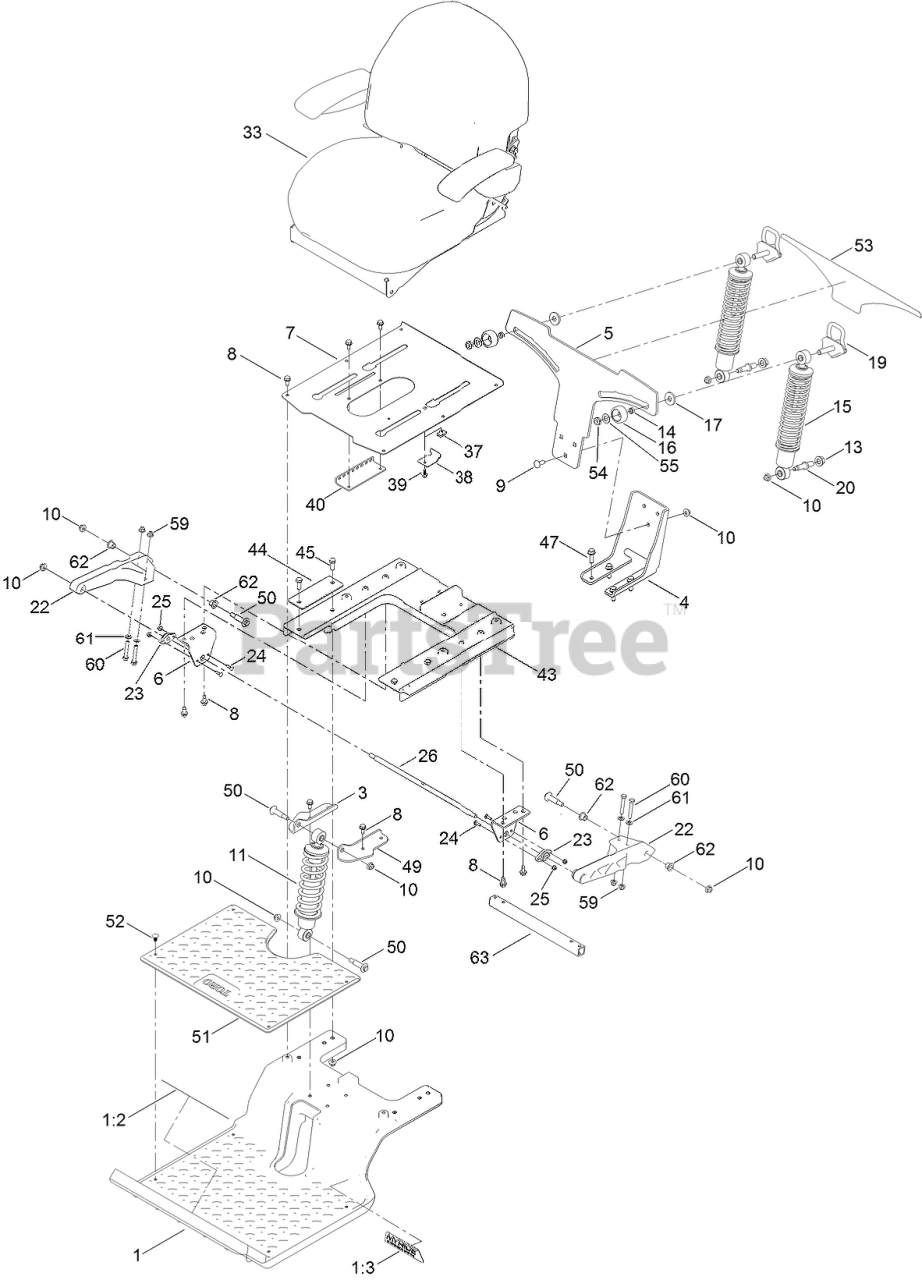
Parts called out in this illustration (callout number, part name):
1	SUBFRAME-FRONT
1:2	DECAL-DANGER
3	BRACKET-SHOCK MOUNT, UPPER (RH)
4	BRACKET-MOUNT, LOWER
5	BRACKET-MOUNTING, SHOCK
6	BRACKET-MOUNT, SWING ARM
7	PAN-SEAT
8	SCREW-HWHTF
9	BOLT-CARR
10	NUT-HF, NI
11	SHOCK/SPRING ASM
13	NUT-HF
14	BEARING-SLEEVE
15	SHOCK/SPRING ASM
16	KNOB-LOCK, CAM
17	WASHER-PLASTIC
19	CAM LOCK ASM
20	BOLT-SHOULDER
22	TRAILING ARM
23	BEARING-FLANGE
24	SCREW-CARR
25	NUT-HF
26	ROD-PIVOT
33	SEAT ASM
38	BRACKET-STOP, SEAT
39	SCREW-HHF
40	BRACKET-LATCH, SEAT
43	SUBFRAME-REAR
44	PLATE-BACKER
45	SCREW-HH
47	SCREW-HWH, THD ROLL
49	BRACKET-SHOCK MOUNT, UPPER (LH)
50	BOLT-SHOULDER
51	FLOORMAT
52	PLUG-PLASTIC
53	DECAL-ADJUSTMENT, RIDE
54	NUT-LOCK, NI
55	WASHER-ADJUSTING
59	NUT-HF
60	SCREW-HH
61	WASHER-PLAIN
62	BUSHING-FLANGE
63	TUBE-ARM, TRAILING
